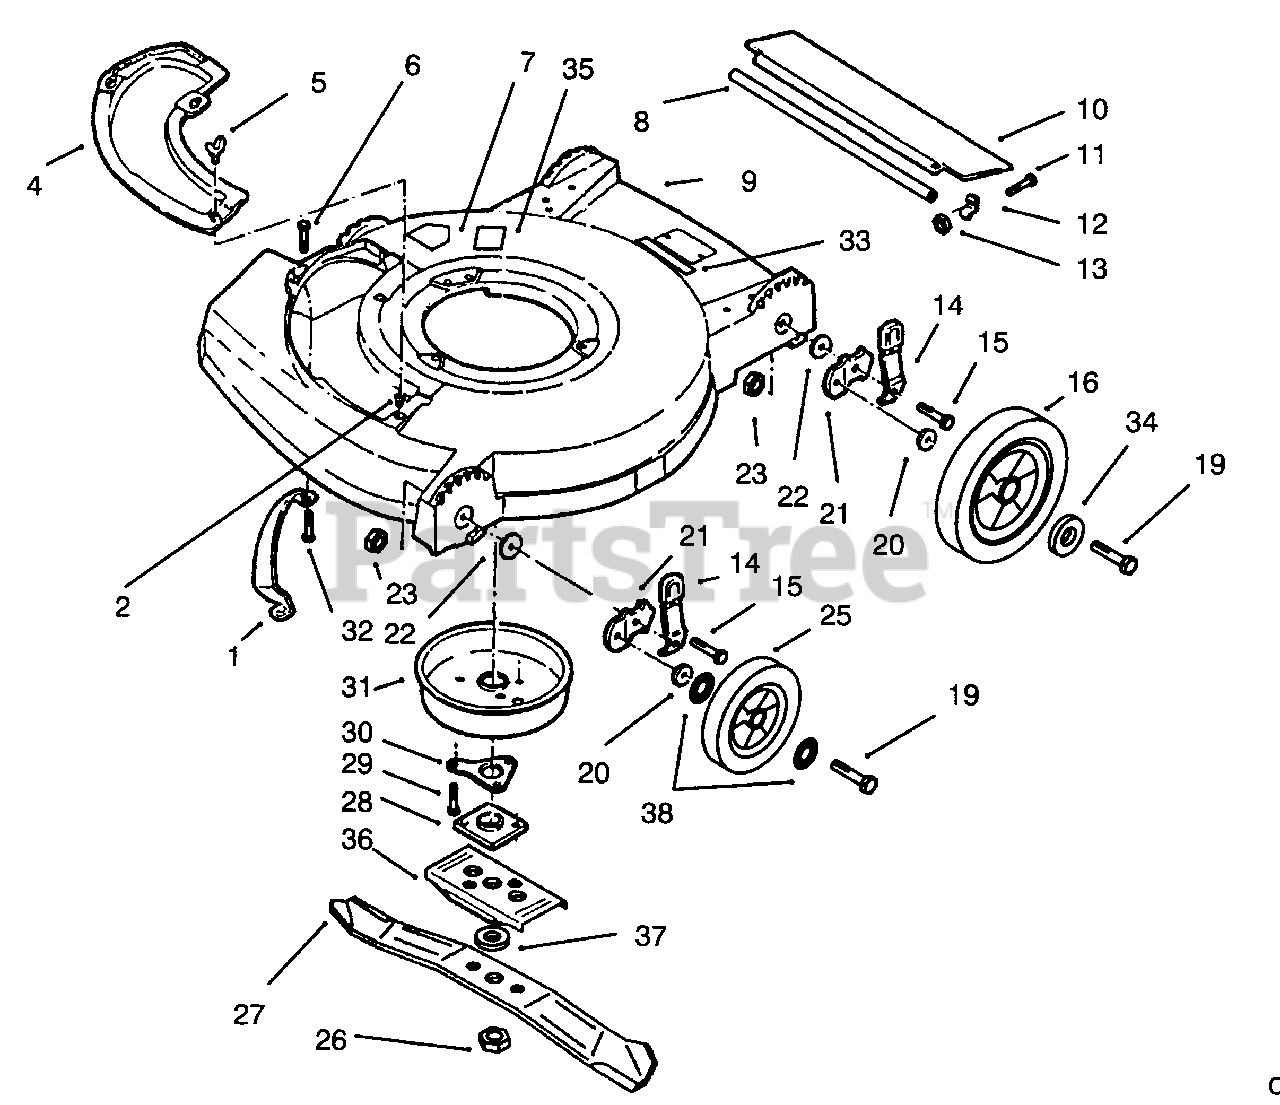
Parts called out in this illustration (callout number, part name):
1	Toe Bar
2	Grommet
4	Cover Plate
5	Screw-Cover Plate
6	Screw-Plate Mounting
7	Decal-Danger (English)
8	Rod-Trailing Shield
9	Housing Assembly (Incl. Ref. #2, 7, 33 & 35))
10	Shield-Trailing
11	Screw-Trailing Shield
14	Knob and Spring Assembly
15	Bolt-Shoulder
16	Wheel-Rear 8"
19	Bolt-Wheel
21	Bracket-Wheel Ht. Adjust
22	Washer-Wheel Ht. Adjust
23	Nut-Wheel Ht. Adjust
25	Wheel-Front 6"
26	Nut
27	Blade 19"
28	Collar and Plate Assembly
29	Screw-Muff. to Muff. Plate
30	Support-Crankshaft
31	Muffler Cover Assembly
33	Decal-Warning (English)
34	Washer-Wheel Bolt
35	Decal-Spark Plug
36	Stiffener-Blade
38	Washer-Felt
